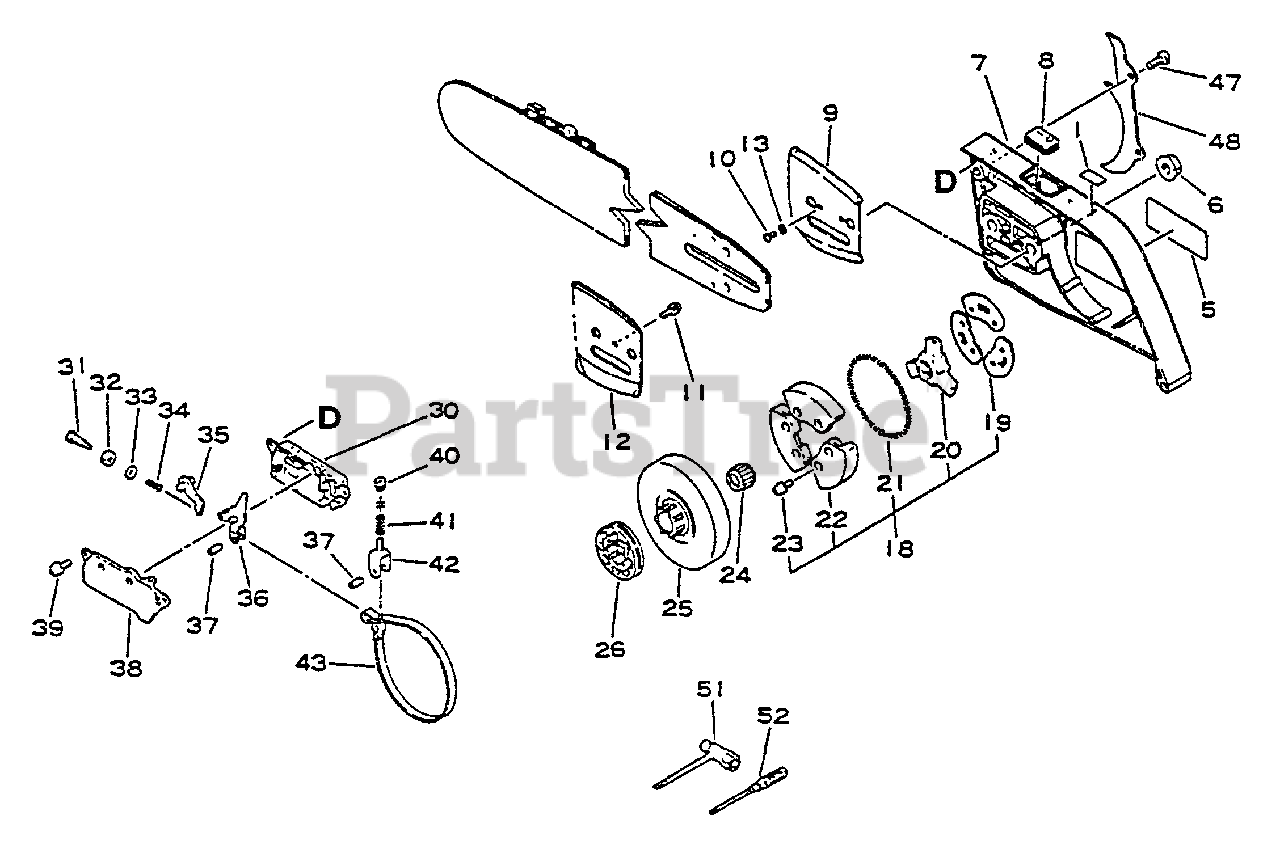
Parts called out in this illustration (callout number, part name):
1	LABEL - CAUTION
5	LABEL - ECHO
6	NUT - FLANGE
7	GUARD, SPROCKET
9	PLATE, GUIDE - OUTER
10	SCREW - 3X6
11	SCREW - 4X8
12	PLATE, GUIDE - INNER
13	LOCKWASHER - 3
18	CLUTCH ASSY
19	PLATE, CLUTCH
20	HUB, CLUTCH
21	SPRING, CLUTCH
22	CLUTCH SHOE SET
23	SCREW - 4X8
24	BEARING, NEEDLE
25	DRUM, CLUTCH
26	SPROCKET, RIM
30	COVER, BRAKE
34	SPRING, BRAKE
35	STOPPER, BRAKE
36	LEVER, BRAKE
37	PIN - SPRING
38	COVER, BRAKE
39	SCREW - 4X10
42	ADJUSTER, BRAKE BAND
43	BAND, BRAKE
48	SPIKE KIT
51	T-WRENCH - 13X19mm
52	SCREWDRIVER
